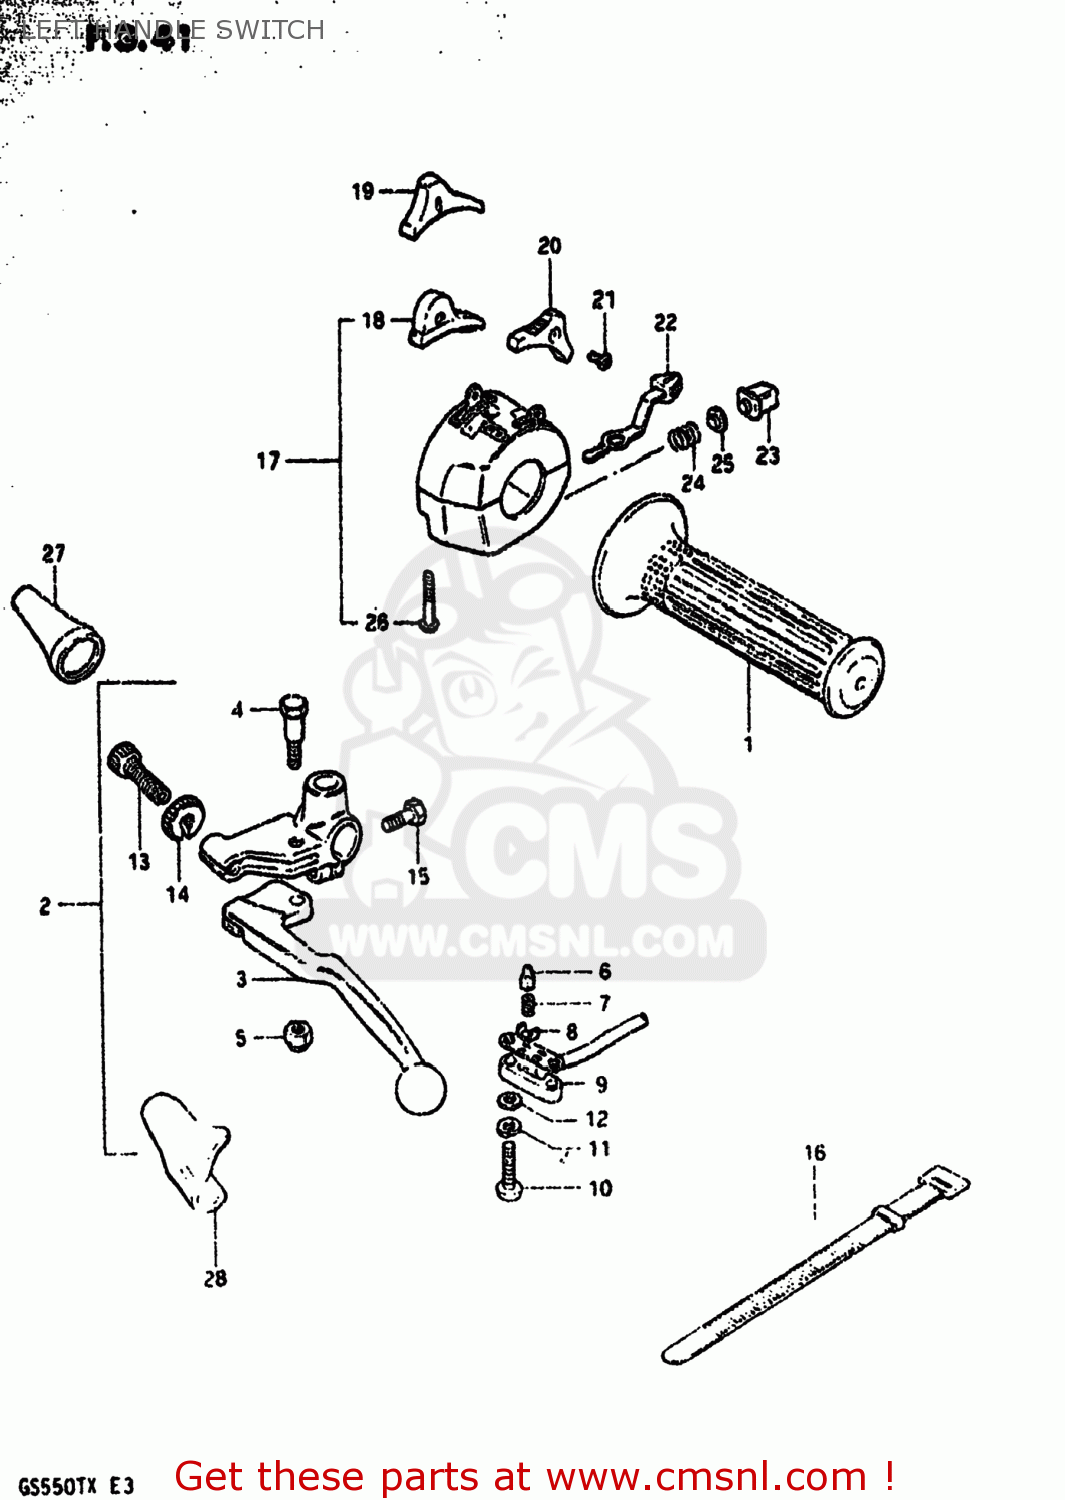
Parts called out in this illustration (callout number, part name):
1	GRIP,LEFT
2	LEVER ASSEMBLY
3	LEVER,CLUTCH
4	BOLT,LEVER
5	NUT 6MM
6	HOLDER
7	SPRING
8	PLATE
9	COVER,FR BK TERMINAL BASE
10	SCREW
11	LOCK WASHER
12	WASHER
13	ADJUSTER,CABLE
14	NUT,CABLE ADJUSTER
15	BOLT,CLUTCH LEVER HOLDER
16	CLAMP(L:120)
17	SWITCH ASSY,HANDLE,L
18	KNOB,STOP
19	KNOB,LIGHTING SWITCH
20	KNOB,DIMMER SWITCH
21	SCREW
22	KNOB,TURNSIGNAL
23	BUTTON,HORN
24	SPRING
25	CONTACT
26	SCREW
27	BOOT,CLUTCH CABLE
28	COVER,CLUTCH LEVER
